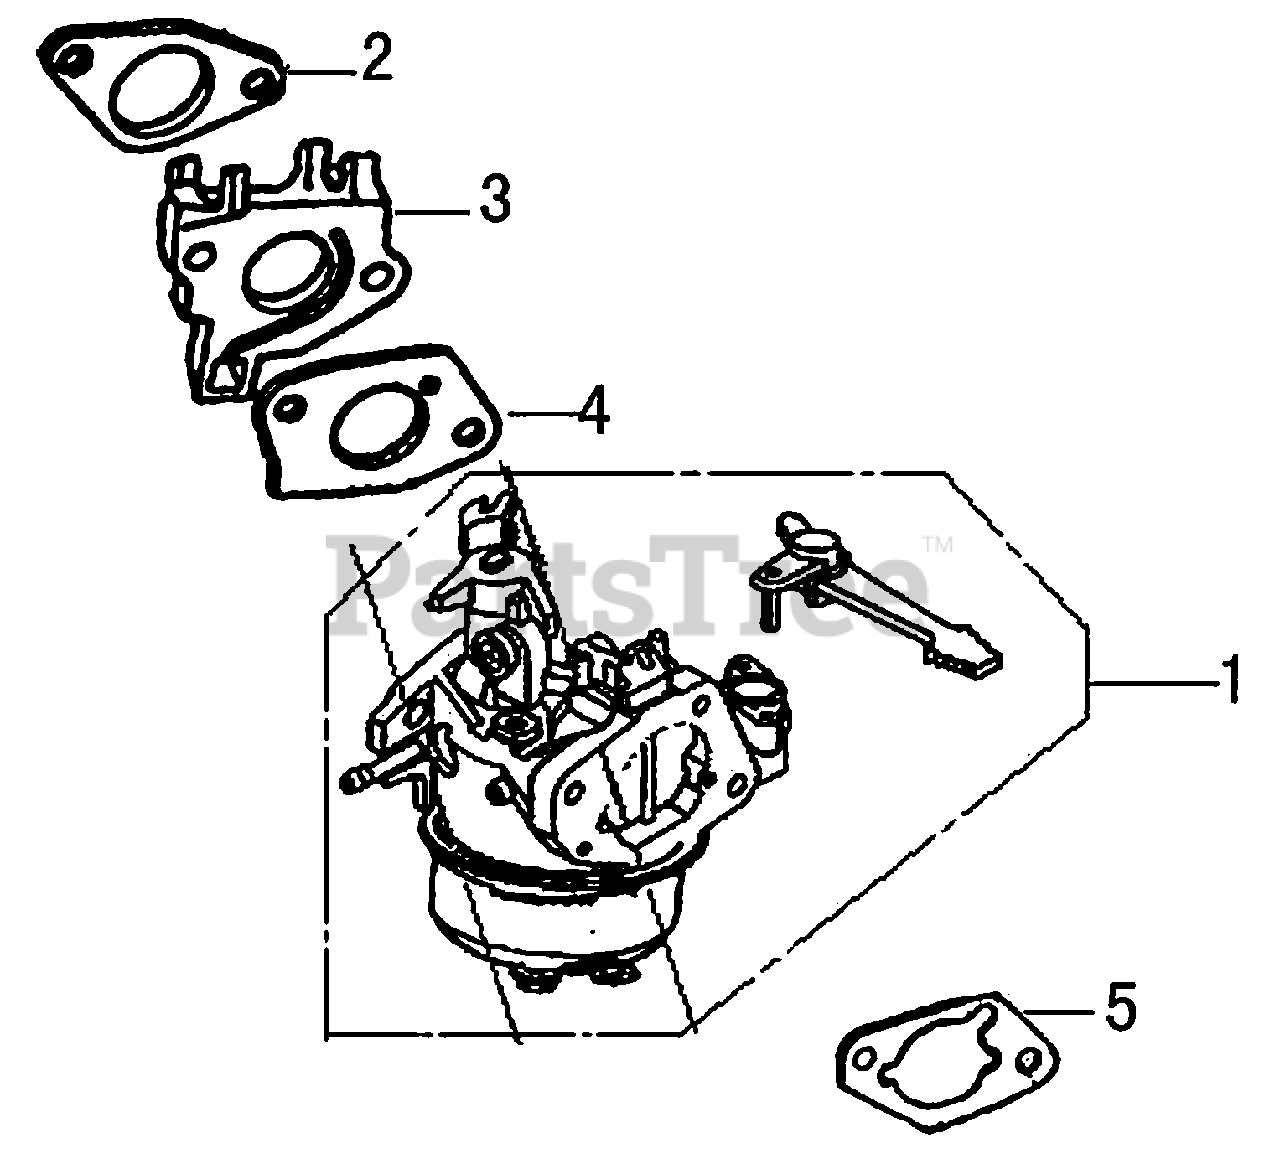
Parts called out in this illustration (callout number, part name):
1	CARBURETOR
2	GASKET CARBURETOR
3	INSULATOR, CARBURETOR
4	GASKET, INSULATOR
5	GASEKET, AIR CLEANER
